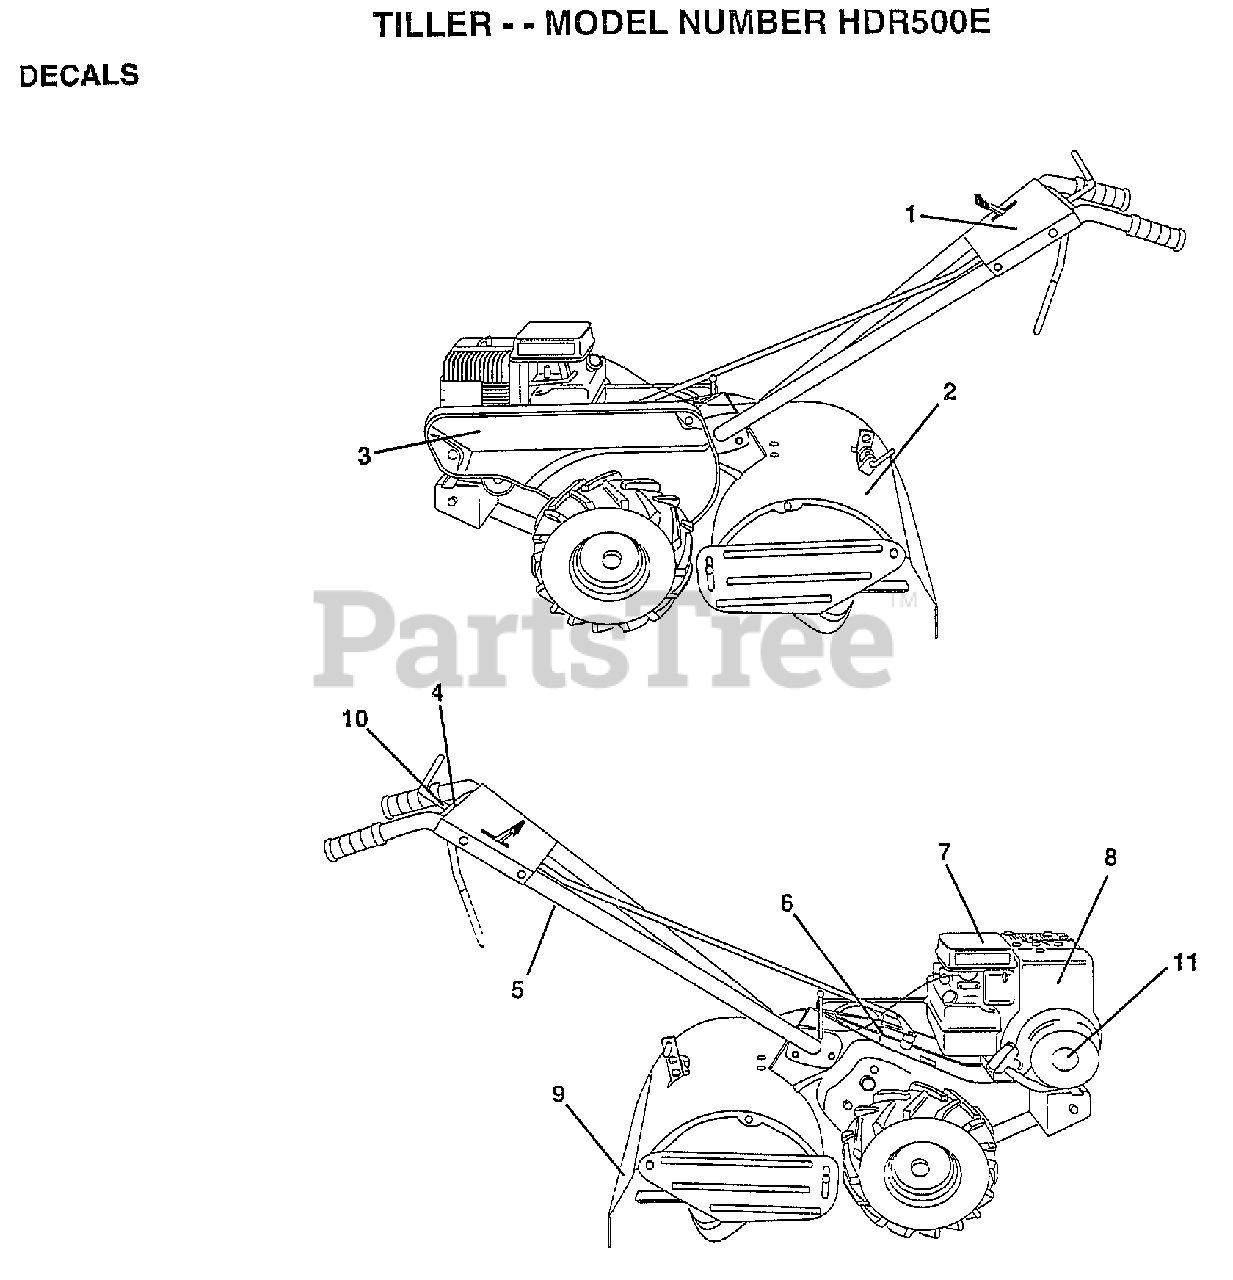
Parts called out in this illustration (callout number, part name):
1	"DECAL PANEL,CTRL"
2	"DECAL SHIELD,TINE"
3	"DECAL GUARD, BELT"
4	DECAL.CONTROL
5	DECAL.HAND.PLACE
6	DECAL CRT
7	DECAL.CAUTION.E/S
8	DECAL, BRIGGS & STRATTON
9	DECAL.WARN.ROT.TI
10	DECAL REVERSE
11	DECAL, 5 HP
